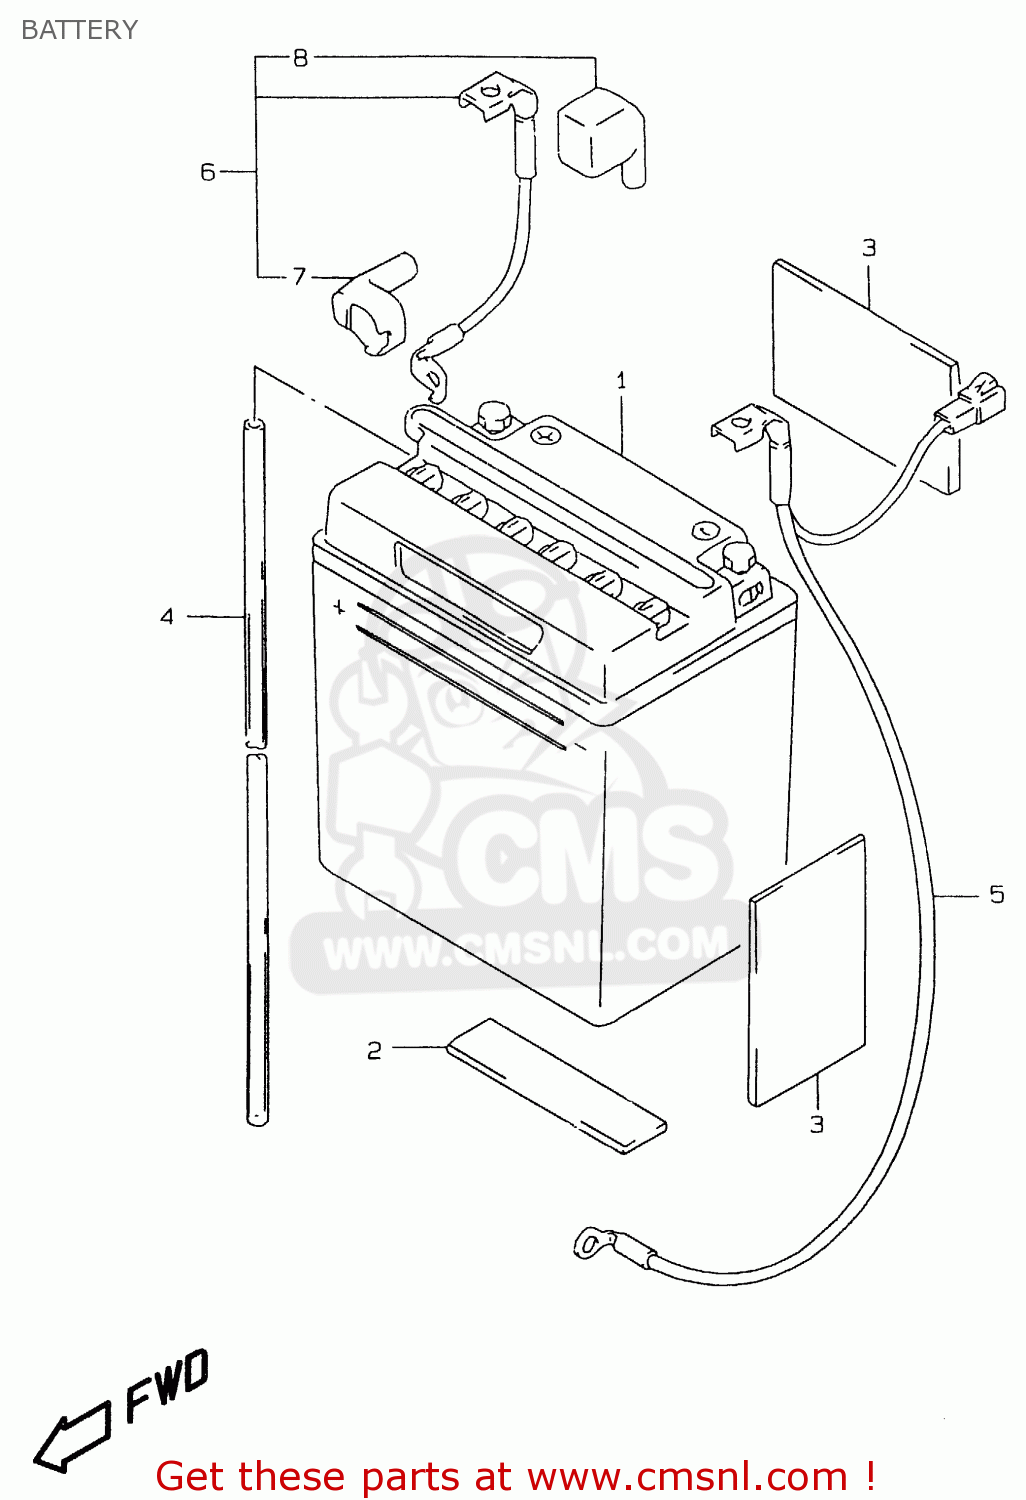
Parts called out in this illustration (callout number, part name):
1	BATTERY ASSY (12V)
2	CUSHION,BATTERY(80X27X3)
3	PROTECTOR(170X95X3.0)
4	HOSE,BATTERY EXHAUST(L:780)
5	WIRE,BATTERY MINUS LEAD
6	WIRE,BATTERY PLUS LEAD
7	CAP,STARTER RELAY TERMINAL
8	CAP,BATTERY PLUS TERMINAL
